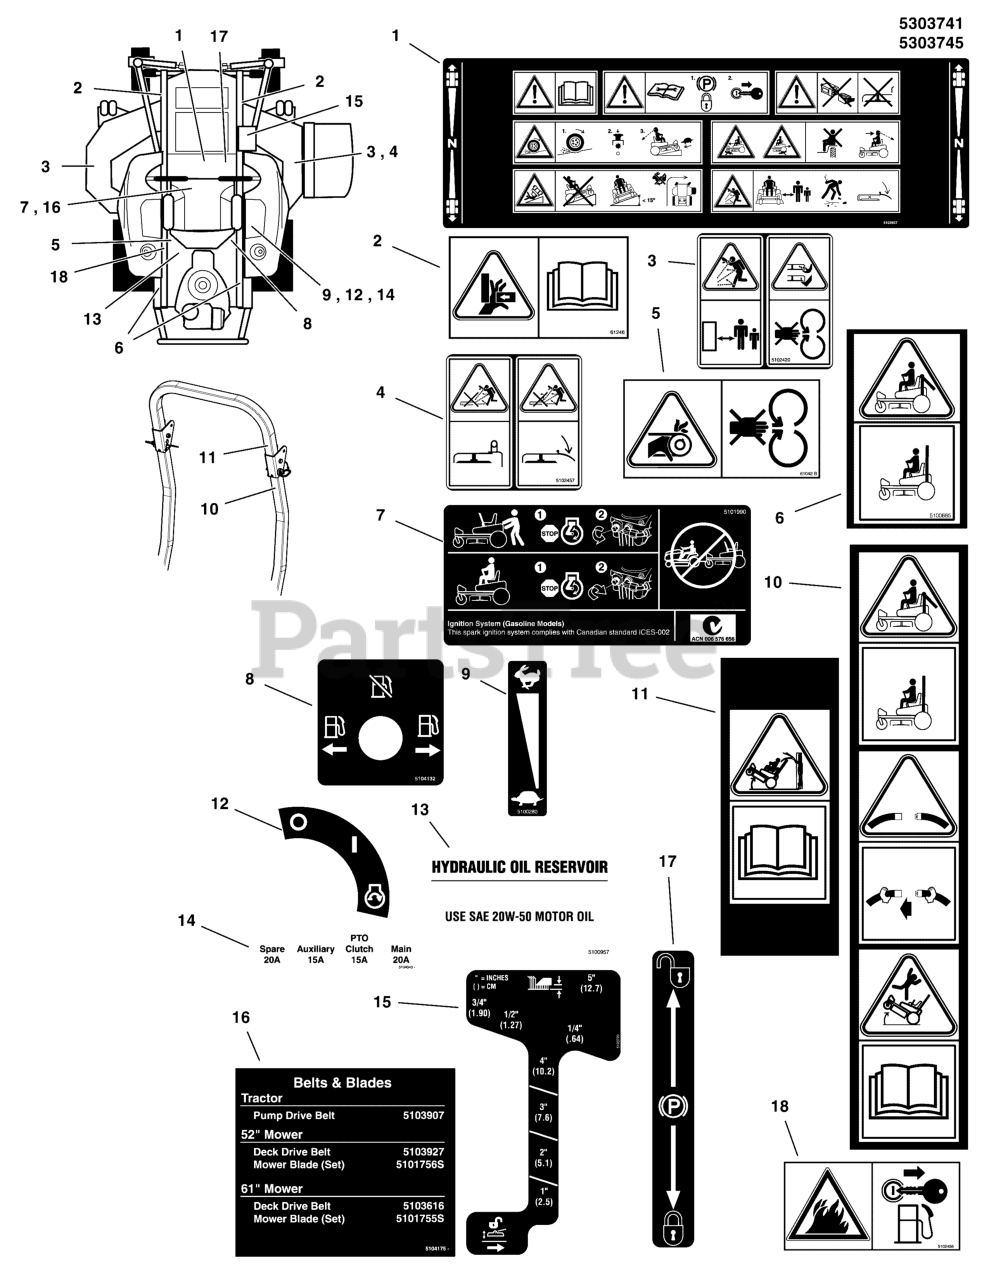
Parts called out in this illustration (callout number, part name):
1	DECAL, MAIN SAFETY, ANSI CE
2	DECAL, PINCH POINT, CE
3	DECAL, DANGER, MOWER DECK, ANSI EXP
4	DECAL, DANGER DISCHARGE ANSI EXPORT
5	DECAL, CE DANGER
6	DECAL, WARNING, ROLLBAR, CE
7	DECAL, TRANSAXLE RELEASE, S200XT
8	DECAL, FUEL VALVE, IS2100Z
8	DECAL, FUEL VALVE
9	DECAL, THROTTLE CONTROL
10	DECAL, SAFETY, CE ROPS
11	DECAL, SAFETY, CE ROPS, OBS
12	DECAL, IGNITION SWITCH
13	DECAL, HYDRAULIC OIL, SAE 20W50
14	DECAL, FUSE LOCATION, IS2100
15	DECAL, CUT HEIGHT, IS700/ZTS700
16	DECAL, BELT & BLADE, IS2100Z (V2)
17	DECAL, PARKING BRAKE SYMBOLS
18	DECAL, FIRE ANSI EXPORT
